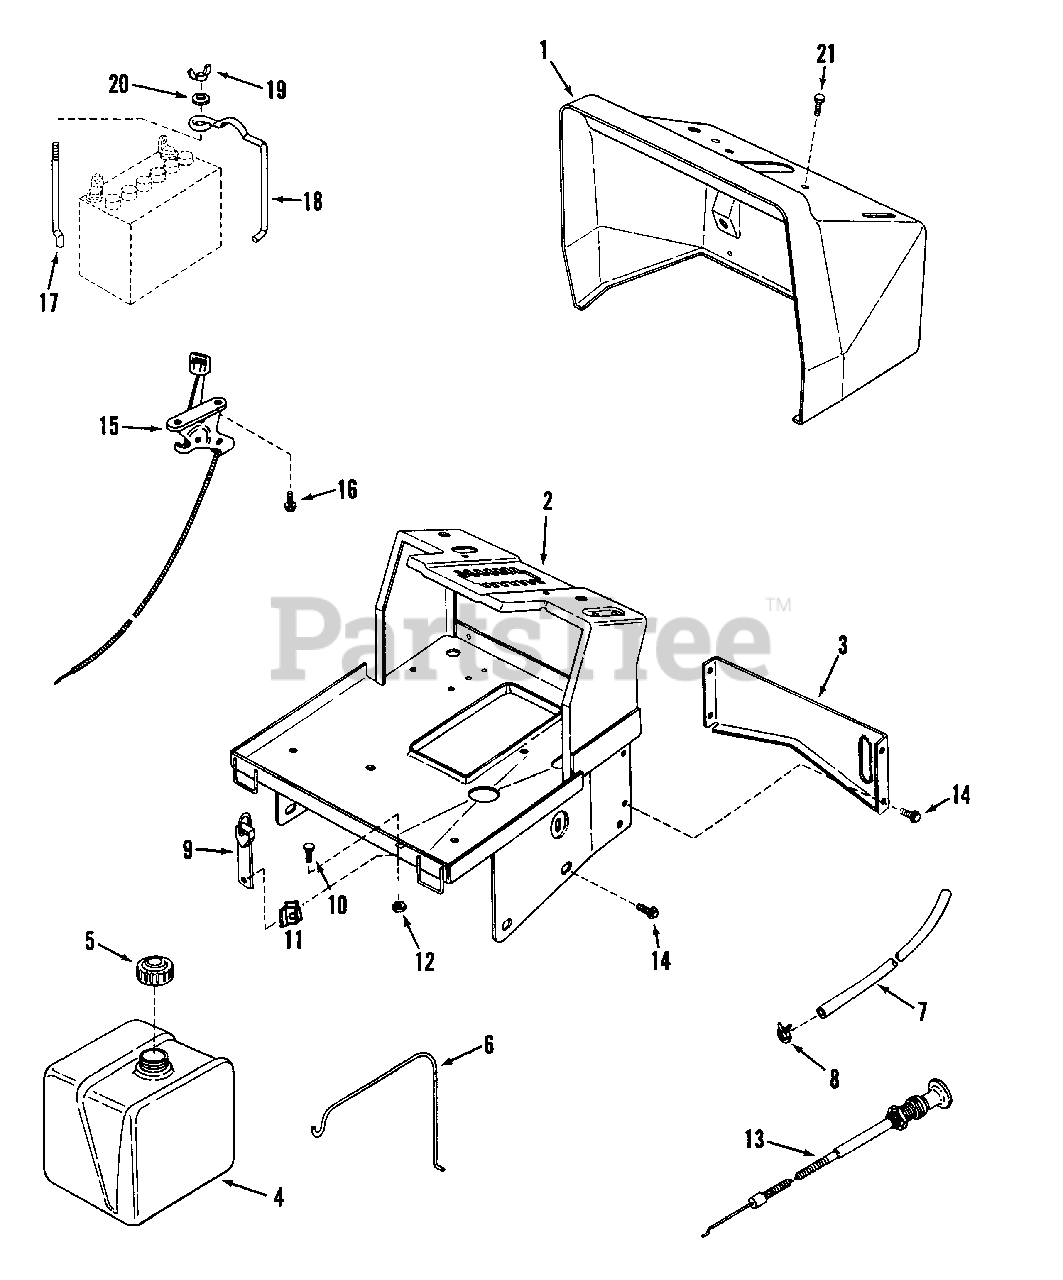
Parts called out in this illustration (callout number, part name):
1	PANEL, Dash
2	PEDESTAL
3	BRACKET, Lower Dash
4	TANK, Fuel
5	CAP, Fuel Tank Filler
6	HOLD-DOWN, Fuel Tank
7	LINE, Fuel (12-1/2" Long)
8	CLAMP, Fuel Line
9	STRAP, Tank Hold Down
10	BOLT, 1/4-20 x 5/8" Flat Head Carriage, Grade 2
11	CLIP, Hood Retainer
12	NUT, 1/4-20 Hex Flange Lock, Grade 5
13	CONTROL, Choke Cable (29")
14	SCREW, 5/16-18 x 5/8" Hex Washer Self-Tap
15	CONTROL, Throttle (27-3/4")
16	SCREW, #10-24 x 1/2" Hex Washer Self-Tap (Torx)
17	HOLD-DOWN, Battery
18	CLAMP, Battery
19	WING-NUT, 1/4-20
20	WASHER, 1/4 Flat
21	SCREW, #10-24 x 1/2" Hex Washer Self-Tap
